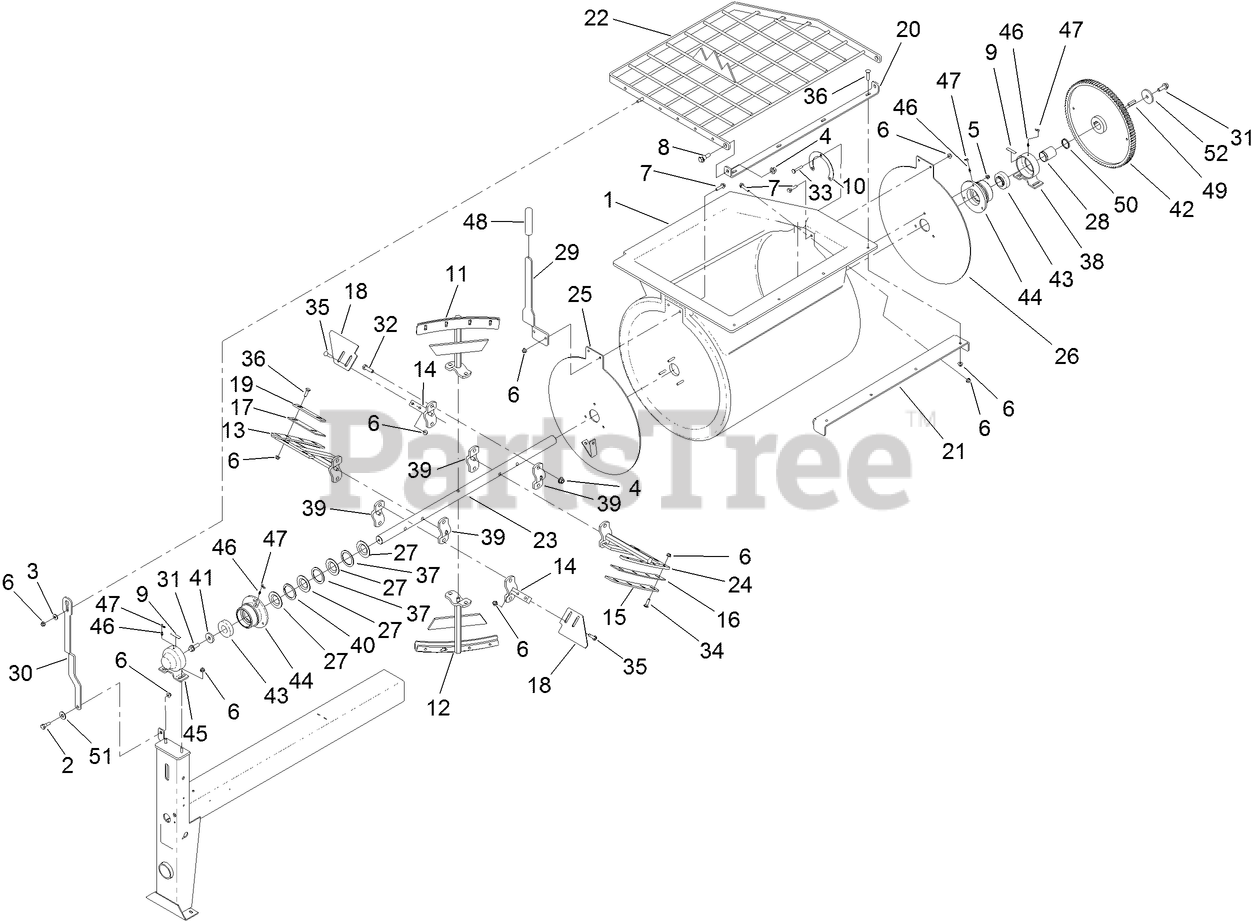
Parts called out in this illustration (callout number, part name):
2	BOLT-SHOULDER
3	WASHER-HARDENED
4	NUT-LOCK
5	NUT-HF, NI
6	NUT-HF, NI
7	SCREW-HHF
8	SCREW-SHOULDER, HHF
9	DECAL-GREASE
10	SPACER-BOLT
11	PADDLE-MID
12	PADDLE-MID
13	PADDLE-FRONT
14	PADDLE-PUSHER
15	BAR-BACKER, TOP
16	BLADE-RUBBER, TOP
17	PADDLE-RUBBER, MIXER END
18	BLADE-SCRAPER
19	BAR-BACKER, END
20	MOUNT-GUARD
21	SUPPORT-GUARD
22	GRATE-6, CUBIC FEET
23	SHAFT-DRUM
24	PADDLE-REAR
25	END-DRUM
26	END-DRUM
27	SEAL-DRUM
28	SPACER
29	HANDLE-DUMP
30	ARM-LIFT, GRATE
31	SCREW-HHF
32	SCREW-HH
33	BOLT-CARR
34	BOLT-CARR
35	SCREW-CARR
36	SCREW-CARR
37	WASHER-FLAT
38	TRUNNION
40	WASHER-SPLIT
41	WASHER-FLAT
42	GEAR-94 TEETH
43	BEARING-BALL
45	TRUNNION-CAPPED
46	FITTING-GREASE
47	CAP-PLUG
48	GRIP-FOAM
49	KEY-SQUARE
50	SPACER-SHAFT, DRUM
51	WASHER-FLAT
52	WASHER-PLAIN
